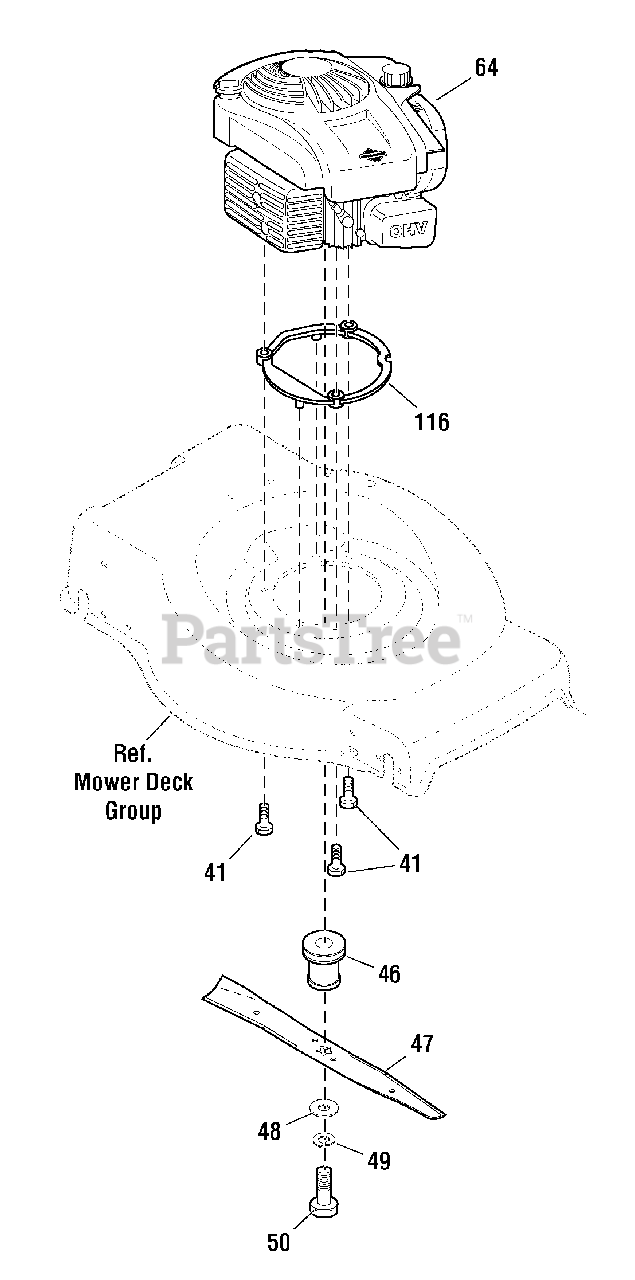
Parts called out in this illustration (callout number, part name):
41	SCREW, Dogpoint, 3/8-16 x 1-1/8
46	ADAPTER, Blade
47	BLADE, 22"
48	WASHER
49	WASHER, Helical
50	BOLT, Hex Head, 3/8-24 x 1-3/8, Gr. 8
64	* ENGINE, B&S Series 625 Model 093J02-0021-F1
116	SPACER, Engine
